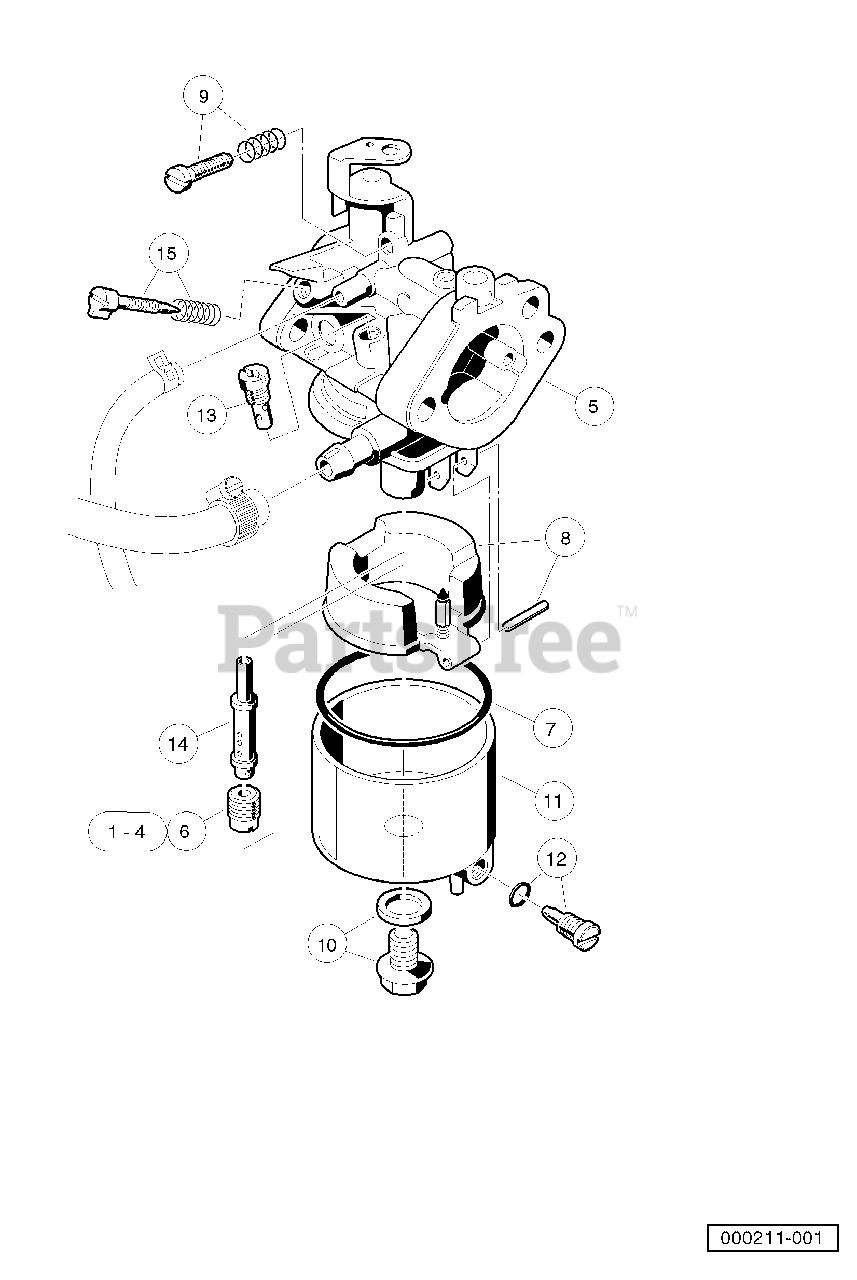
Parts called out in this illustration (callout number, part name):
1	Jet, Altitude, # 72
2	Jet, Altitude, # 75
3	Jet, Altitude, # 78
4	Jet, Altitude, # 80
5	Carburetor Assembly, FE290D
6	Jet, Altitude, # 82
7	Gasket, Carburetor Bowl OHV
8	Float Assembly
9	Screw Assembly
11	Chamber Assembly, Float
12	Screw Assembly
13	Jet, #40 Pilot
14	Nozzle, Main
15	Assembly, Pilot Air Screw
